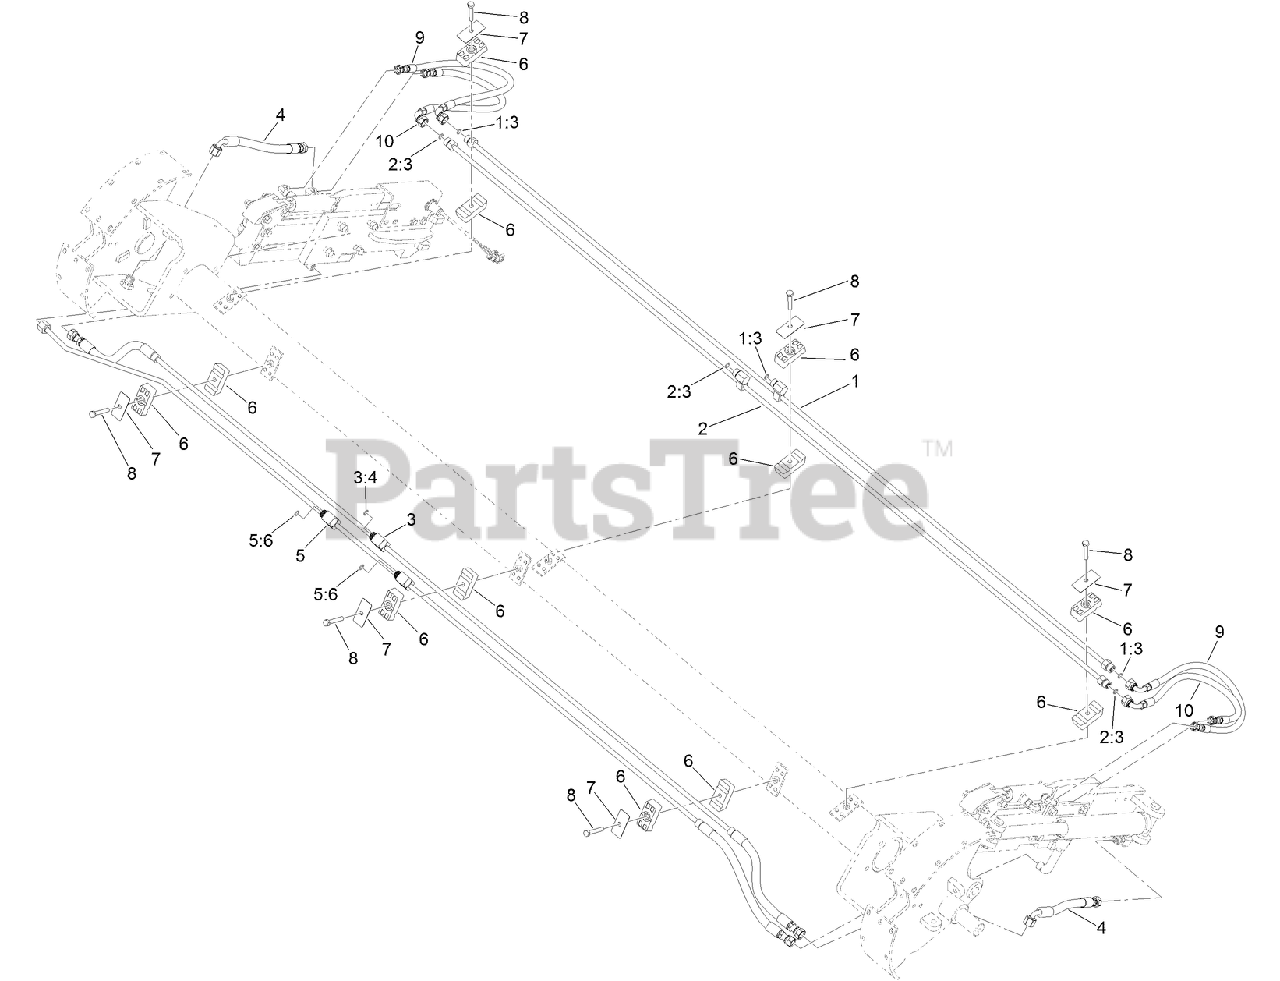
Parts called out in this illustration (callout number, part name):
1	TUBE ASM-HYD
1:3	O-RING
2	TUBE ASM-HYD
2:3	O-RING
3	HYD TUBE-HOSE ASM
3:4	O-RING
4	HOSE ASM-HYD
5	HYD TUBE - HOSE ASM
5:6	O-RING
6	CLAMP-TUBE
7	PLATE-COVER
8	SCREW-HH
9	HOSE ASM-HYD
10	HOSE ASM-HYD
